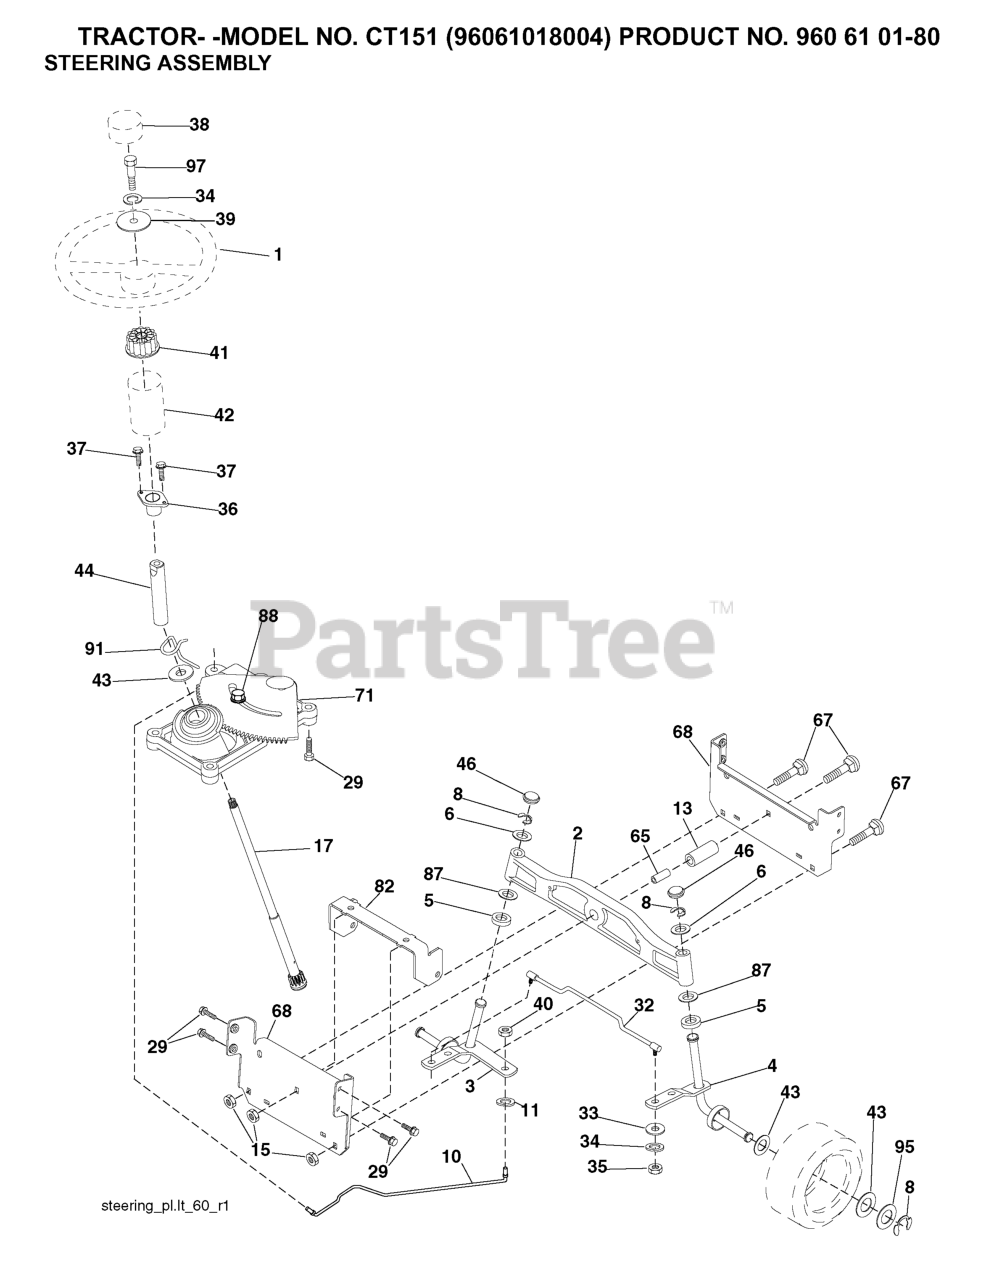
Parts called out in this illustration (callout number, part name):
2	SPRING,BRAKE RETURN
3	PULLEY
4	RETAINING RING LT
5	STRAP TORQUE
6	SCREW 5/16"
8	ROD SHIFT FENDER ADJUST LT
10	PIN COTTER
11	WASH-SHFT PLT LT
13	BOLT 1/4-28X3/4
14	LOCKWASHER
15	BOLT HEX 5/16-18 GR 5
16	NUT.71038.31-18.HEX.NYLOCK
19	NUT
20	BOLT HEX 7/16-20X4-1/4"
21	KNOB.DUCKHEAD.1/2
22	ROD
24	NUT
25	SPRING ROD LT
26	WASHER
27	COTTER PIN
28	ROD, PARKING BRAKE
29	CAP
30	BRKT, MOUNT TRNSAXLE
34	SHAFT, FOOT PEDAL
35	BEARING.NYLON
37	DRIVE PIN
38	PULLEY.FLAT
42	WASHER
47	IDLER PULLEY
48	BELLCRANK, CLUTCH
49	RETAIN BELT
50	BOLT.3/8-16X1.50
53	LINK.CLUTCH.7.66.2005
55	SPRING, RETURN LT
56	SCREW.3/8-16
57	V-BELT.KEV.111"
62	PEDAL COVER T
63	PULLEY.ENGINE.CVX.LT
65	LOCKWASHER
66	KEEPER BELT ENGINE
77	SQUARE KEY
79	KEY STD (1373) DANA
82	SHIFT SPRING
83	WASHER
96	RETAINER M
120	NUT LOCK FLG 3/8-16 UNC
150	BUSHING.BELLCRANK.GRD.DR
151	WASHER 12/32X2X10GA
156	WASHER.SRRTD.5/16
158	BRACKET
159	RB HUB.SHIFT
161	BOLT
162	NUT.CROWNLOCK.1/4
165	RP BRACKET
166	CAPSCREW.HXHD.FLG.5/16-18X.625
167	BRACKET.SUPT.SHIFT.CRD
168	BOLT.SHOULDER.5/16-18X
172	SHAFT
181	BRACKET
182	BELT GUIDE
183	PULLEY.V-IDLER.GRND.DR
187	BOLT.5/16-18X1.25
207	WASHER NYL
214	LEVER
243	BRACKET, ANTI-ROTATION
254	SCREW 3/8-16X1
255	SHAFT
258	CLIP RETAINER
261	FLAT IDLER PULLEY
263	SCREW, 3/8-16X3/4
266	PROTECTOR
268	GUARD MUFFLER
275	WASHER
292	SPACER
295	PULLEY IDLER COMPOSITE
